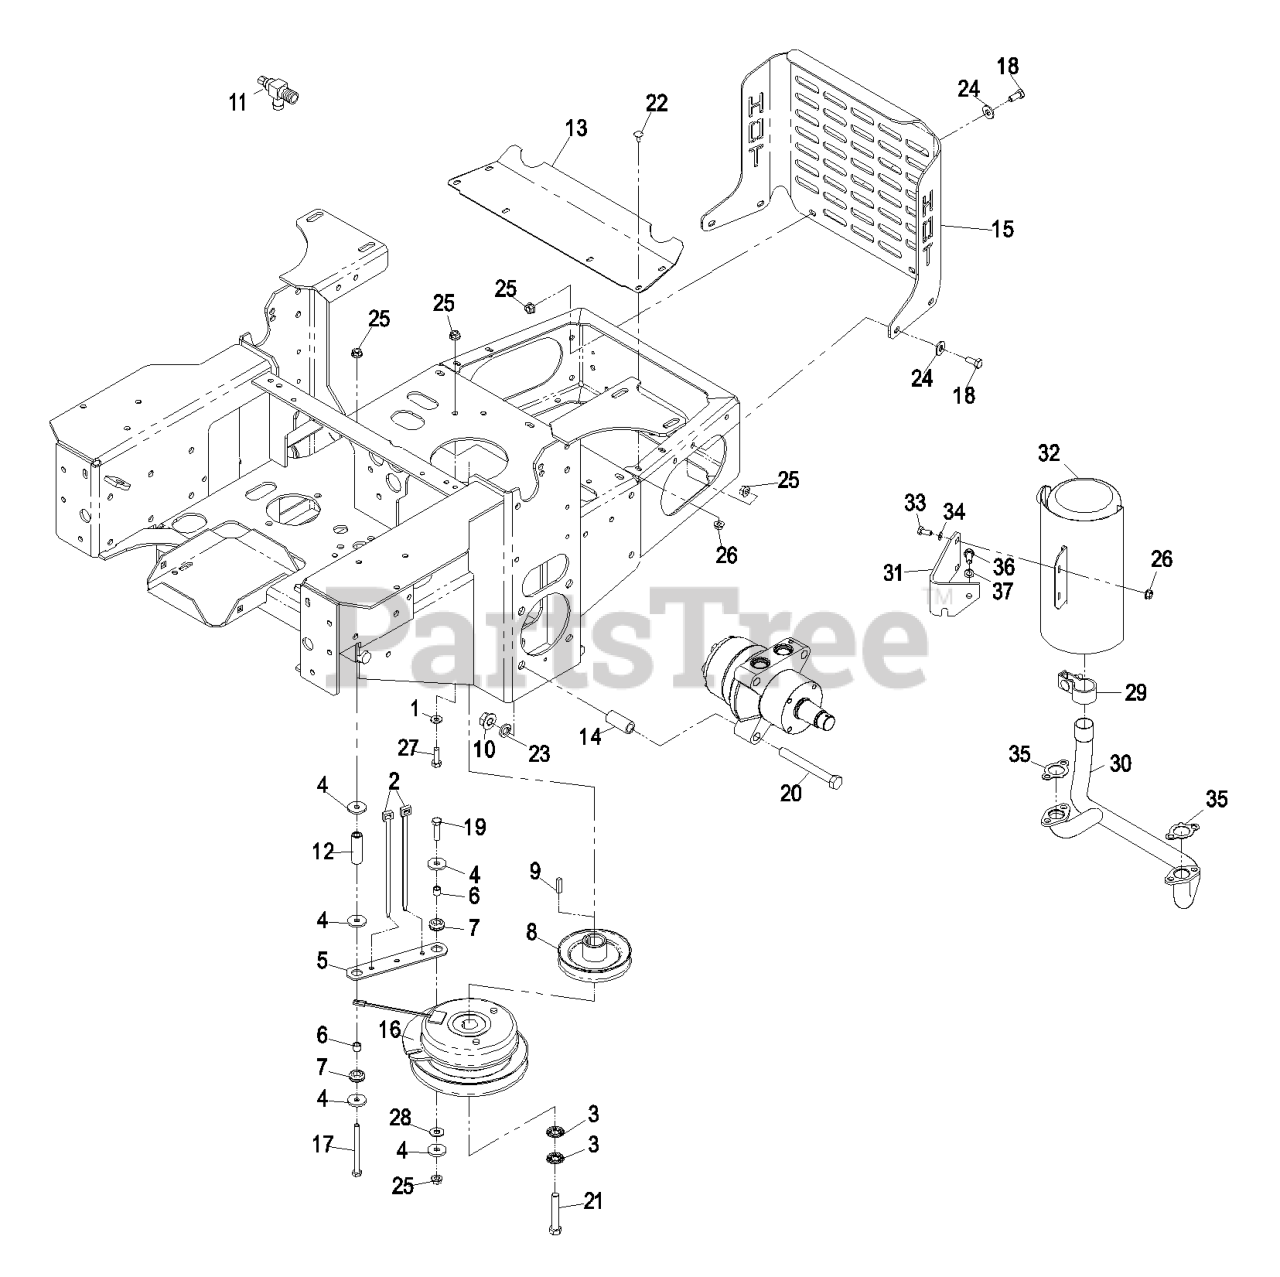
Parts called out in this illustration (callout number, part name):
1	WASHER-SPRING
2	TIE-PLASTIC
3	WASHER-SPRING
5	STRAP-CLUTCH, BRAKE
7	GROMMET
10	NUT-HHF
11	VALVE-DRAIN, OIL
13	DEFLECTOR-SHORT
14	SPACER-WHEEL, SHORT
15	BUMPER-REAR
17	SCREW-HH
18	SCREW-HH
19	SCREW-HH
20	SCREW-HH
21	SCREW-HH
22	SCREW-CARR
23	WASHER-LOCK
24	WASHER-FLAT
27	SCREW-HH
28	WASHER-FLAT
29	CLAMP-MUFFLER, 1.25 FLAT
31	BRACKET,EXHAUST 21BV
32	MUFFLER
33	SCREW-HH
34	WASHER-SPRING
36	SCREW-HH
37	WASHER-LOCK
